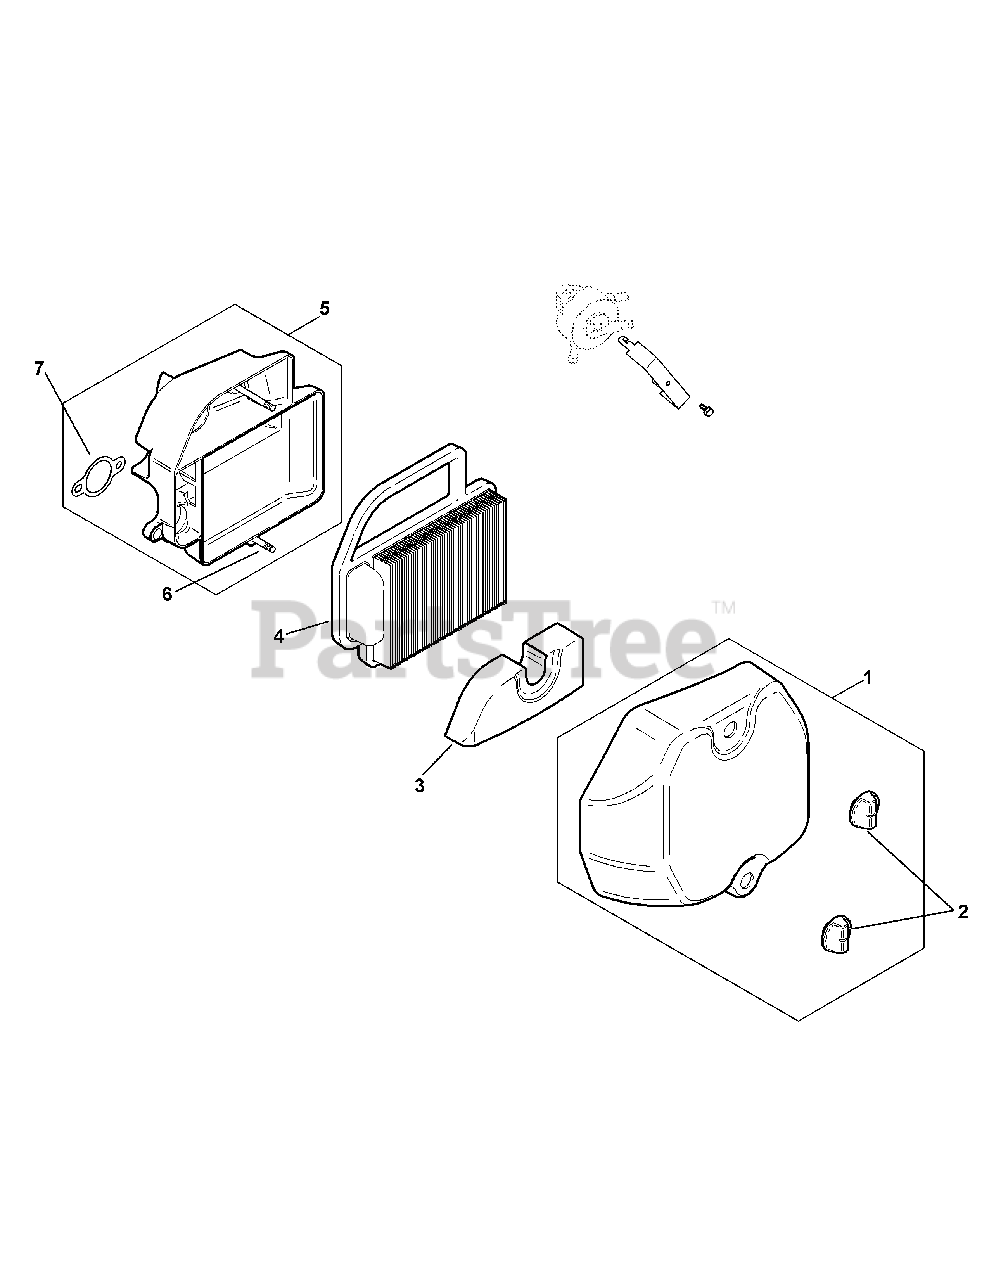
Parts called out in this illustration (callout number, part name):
1	Air Cleaner Cover Kit (Inc. KH-25-341-04-S)
3	Pre-Cleaner Element (Dry)
4	Air Cleaner Element
5	Air Cleaner Base Kit (Inc 6 & 7)
6	Air Cleaner Base Stud
7	Air Cleaner Base Gasket
